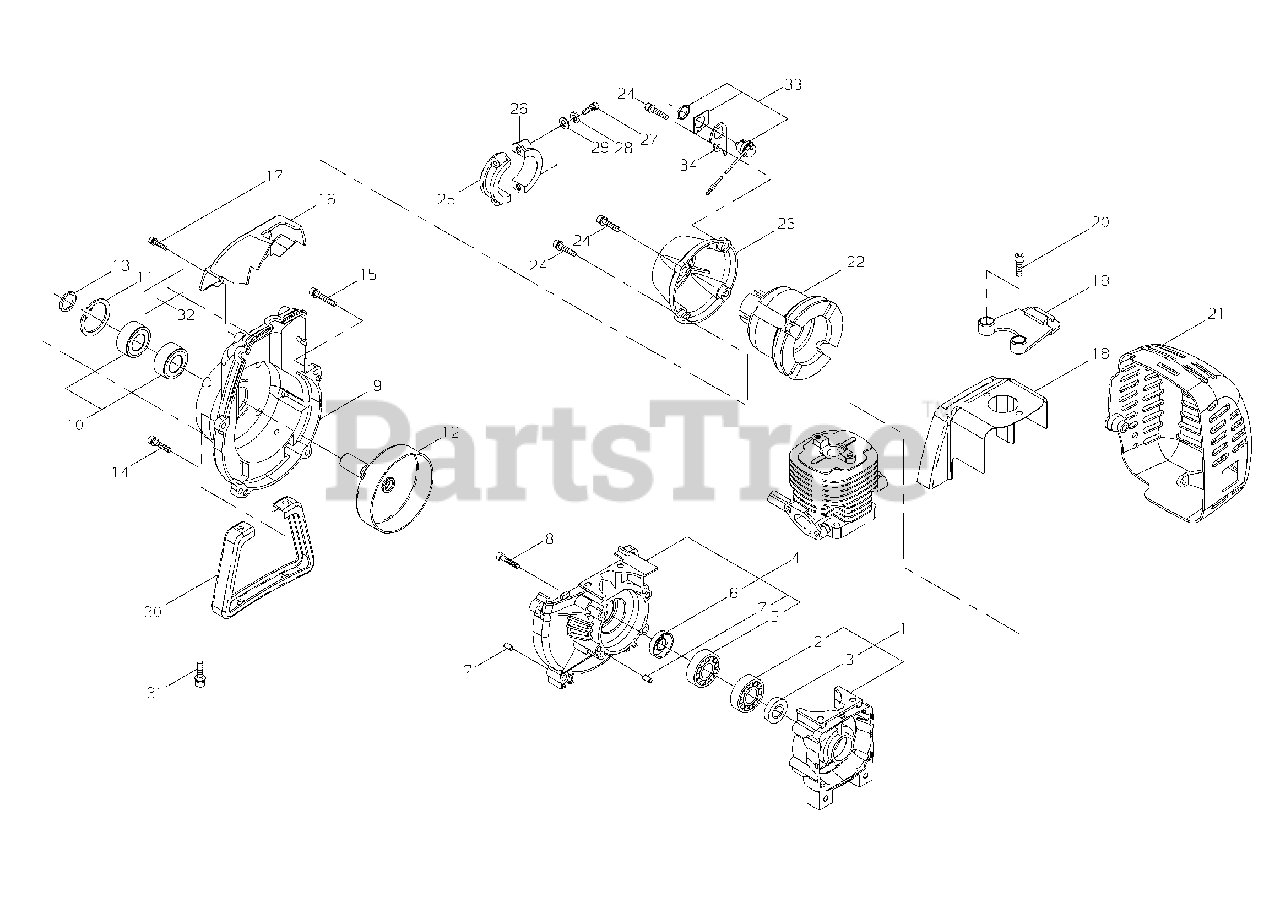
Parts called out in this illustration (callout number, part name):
1	CRANKCASE ASSY - REAR
2	BEARING, BALL - 6202C3
3	SEAL, OIL
4	CRANKCASE ASSY - FRONT
5	BEARING, BALL - 6202C3
6	SEAL, OIL
7	PIN - LOCATING
8	SCREW - 5X30
9	CASE, FAN
10	BEARING, BALL - 6002
11	RING, RETAINING - 32
12	DRUM, CLUTCH
13	RING, RETAINING
14	SCREW - 5X20
15	SCREW - 5X30
16	PROTECTOR
17	SCREW - 4X16
18	COVER, ENGINE
19	STAY
20	SCREW - 5X18
21	COVER, EXHAUST
22	CUSHION
23	CONNECTOR, CAP
24	SCREW - 5X20
25	CLAMP - A
26	CLAMP - B
27	SCREW - 5X25
28	LOCKWASHER - 5
29	WASHER - 5
30	STAND
31	SCREW - 5X16
32	LABEL - TRADE
33	SWITCH, IGNITION
34	BRACKET
